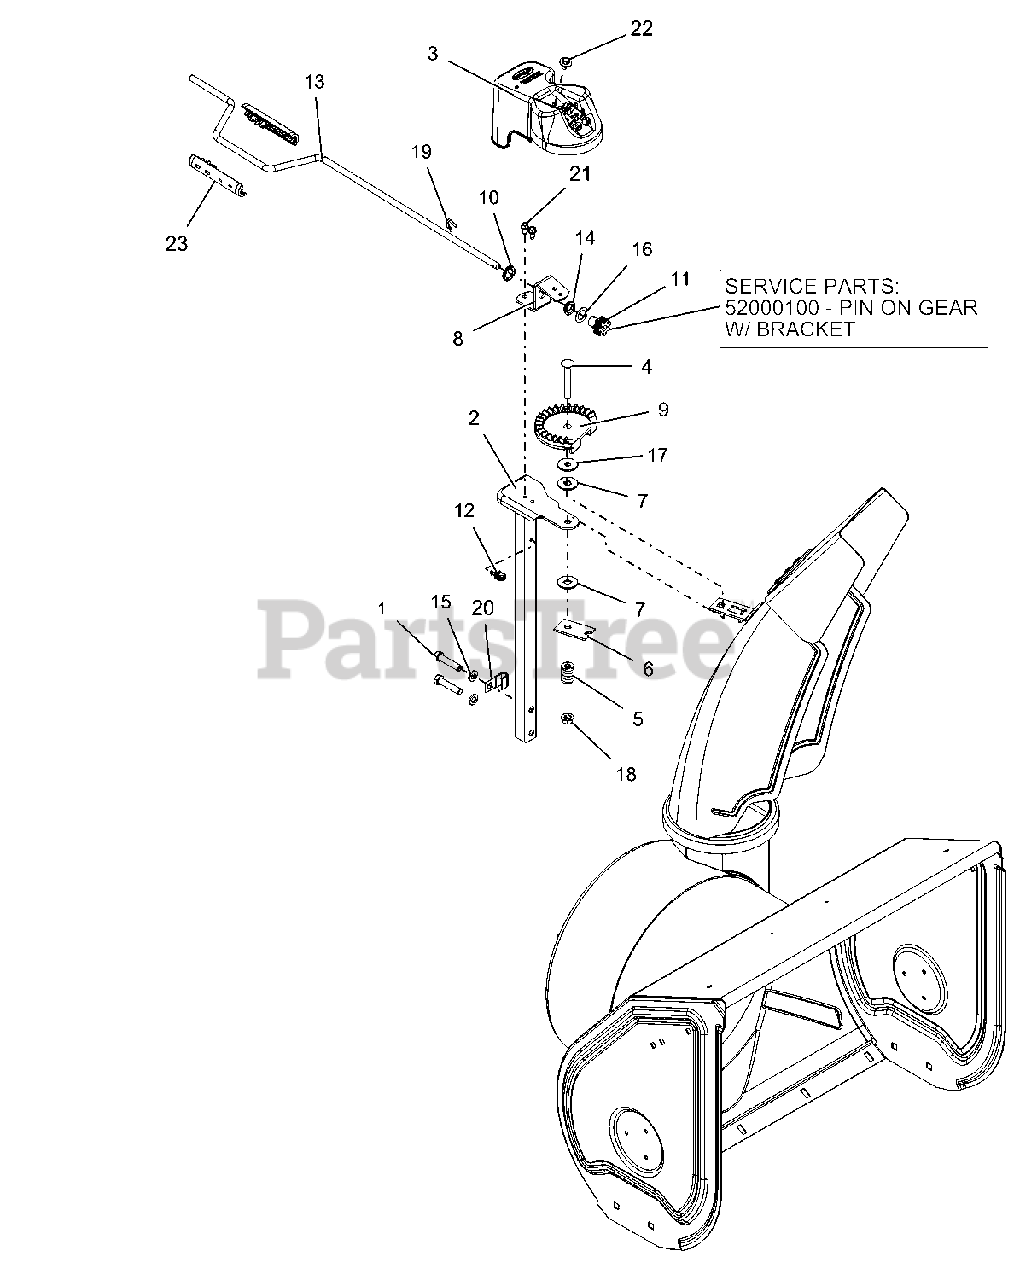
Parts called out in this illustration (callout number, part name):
1	@BLT-HEX .38-16X1.75 GR5 YWZC
2	PEDESTAL, CHUTE - CRANK
3	GEAR COVER ASSY LG SHEAR BOLT
4	@BLT-RDHDSQNK .38-16X2.50 G5YZ
5	SG-COMP .187X.56X1.62
6	PLATE, FRICTION
7	FRICTION WASHER
8	BRACKET, PINION GEAR
9	CHUTE GEAR
10	PUSHNUT .625
11	PINION GEAR W/BRACKET
11	PINION GEAR - CHUTE
12	CLIP, CABLE GUIDE
13	ROD, CHUTE CRANK
14	BUSHING, POLYLINER-.63 SNAPIN
15	@WSHR-LK .38X.094 REG YWZC
16	WSHR-THRST .625 X 1.0 X .03
17	@WSHR-FL-STL .406X1.25X.10 ZC
18	@NUT-LK-TOP-FLG .38-16 YWZC
19	PIN, SPRING CLIP
20	J-CLAMP
21	SCR-TAP .25-20X.50 HWH TR YWZ
22	SCR-TAP .25-20X.50 LGHWH TR YZ
23	KNOB,CHUTE CRANK-DELUXE
